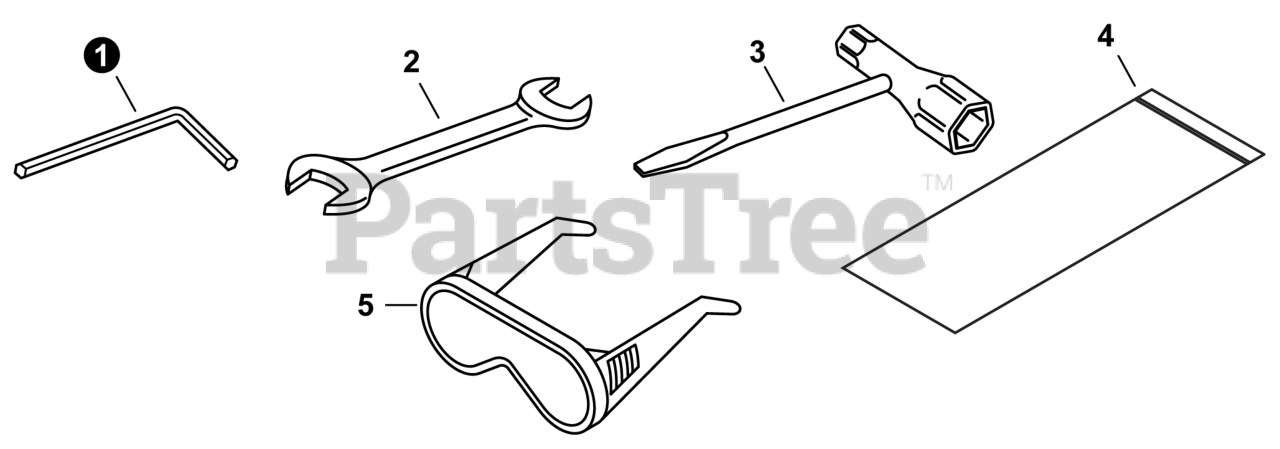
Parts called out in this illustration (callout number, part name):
1	WRENCH, ALLEN 4 MM
2	SPANNER 8×10
3	T-WRENCH 17×19 MM
4	BAG, TOOL
5	GLASSES, SAFETY
